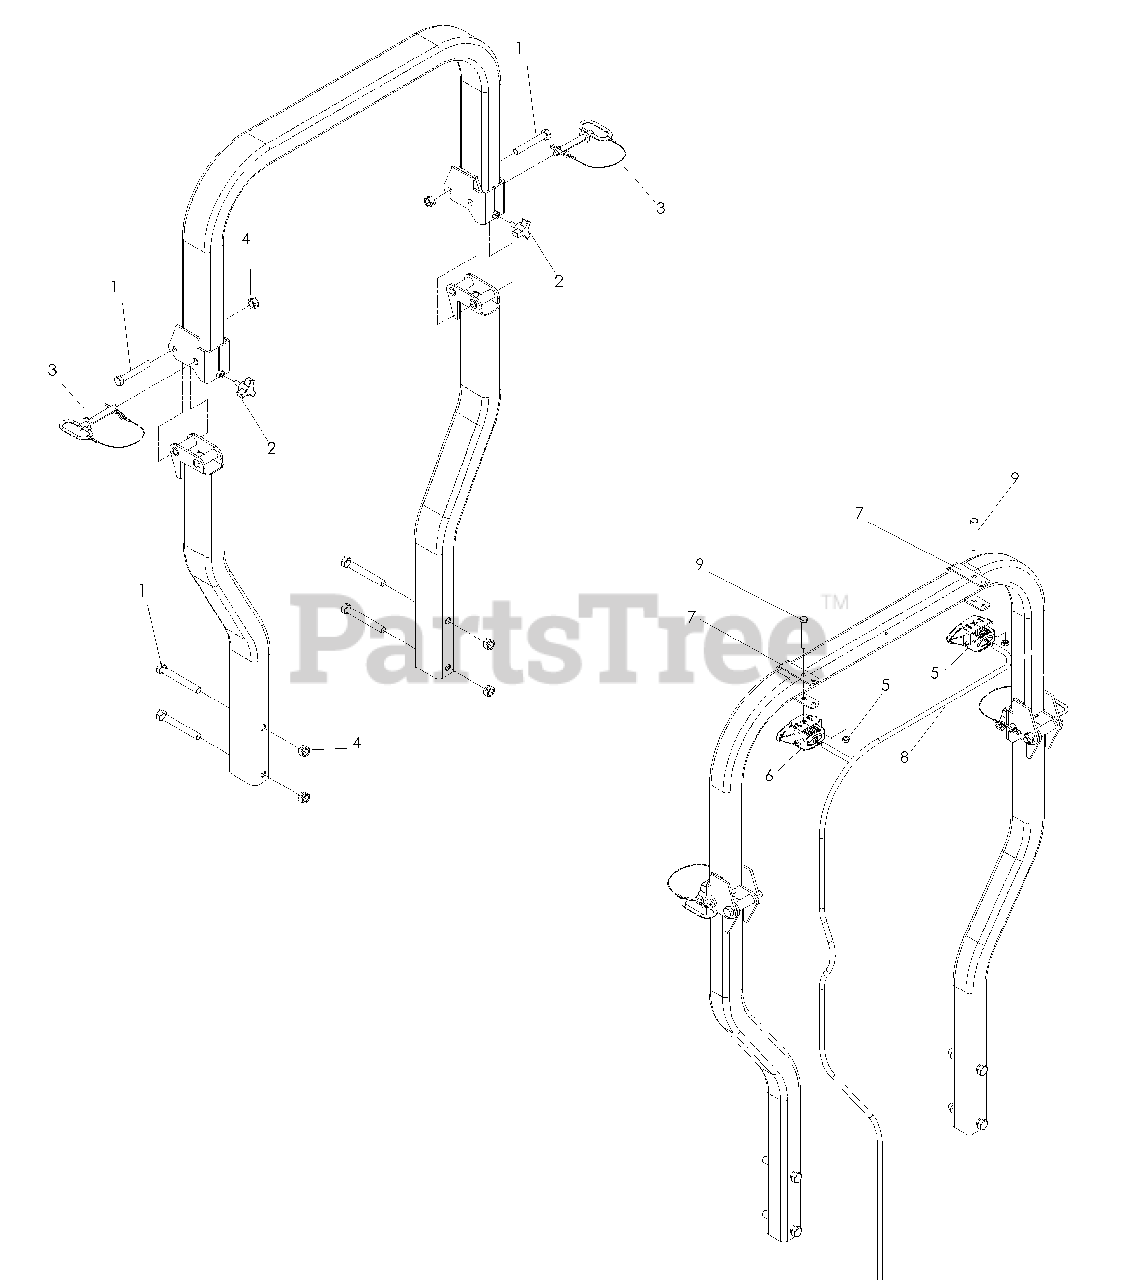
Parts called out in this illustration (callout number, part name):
1	HCS 1/2 C x 3 1/4
2	KNOB w/STUD
3	LANYARD W/PIN 1/2"
4	NUT 1/2-13, CTRLK
5	NUT 5/16-18, JAM
6	LIGHT w/BRKT & HRDWARE
7	MOUNTING BRKT, LIGHT
8	LIGHT HARNESS
9	HCS 5/16 -18 x 2 1/2
